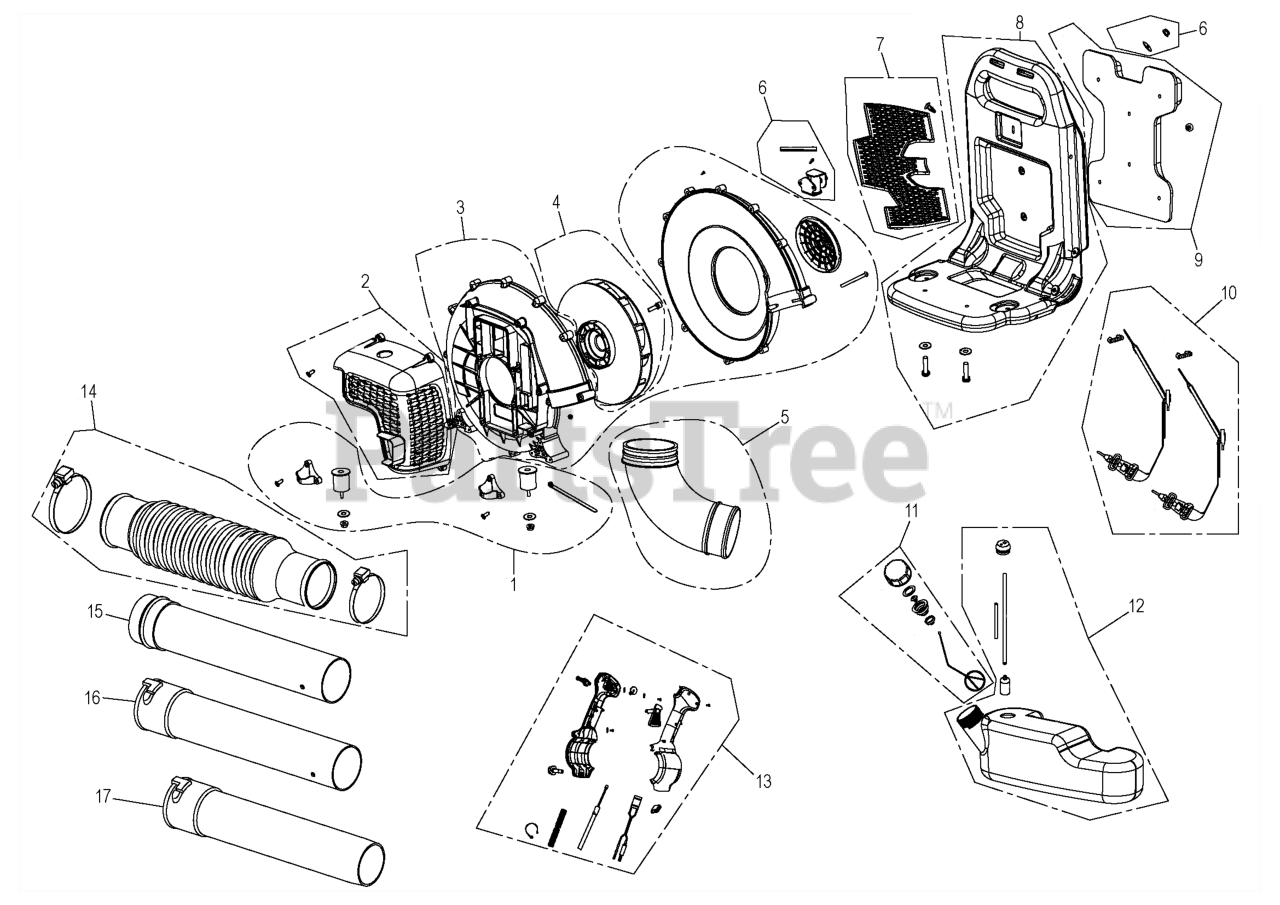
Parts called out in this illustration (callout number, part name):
1	REPAIR KIT DAMPER - LOWER
2	REPAIR KIT ENGINE COVER
3	REPAIR KIT VOLUTE
4	REPAIR KIT FAN
5	REPAIR KIT ELBOW ASSY
6	REPAIR KIT DAMPER - UPPER
7	REPAIR KIT NET
8	REPAIR KIT FRAME ASSY
9	REPAIR KIT PAD ASSY
10	REPAIR KIT HARNESS ASSY
11	REPAIR KIT FUEL CAP ASSY
12	REPAIR KIT FUEL TANK ASSY
13	REPAIR KIT OPERATING LEVER
14	REPAIR KIT HOSE ASSY
15	REPAIR KIT SWIVEL JOINT
16	REPAIR KIT STRAIGHT PIPE
17	REPAIR KIT END PIPE
